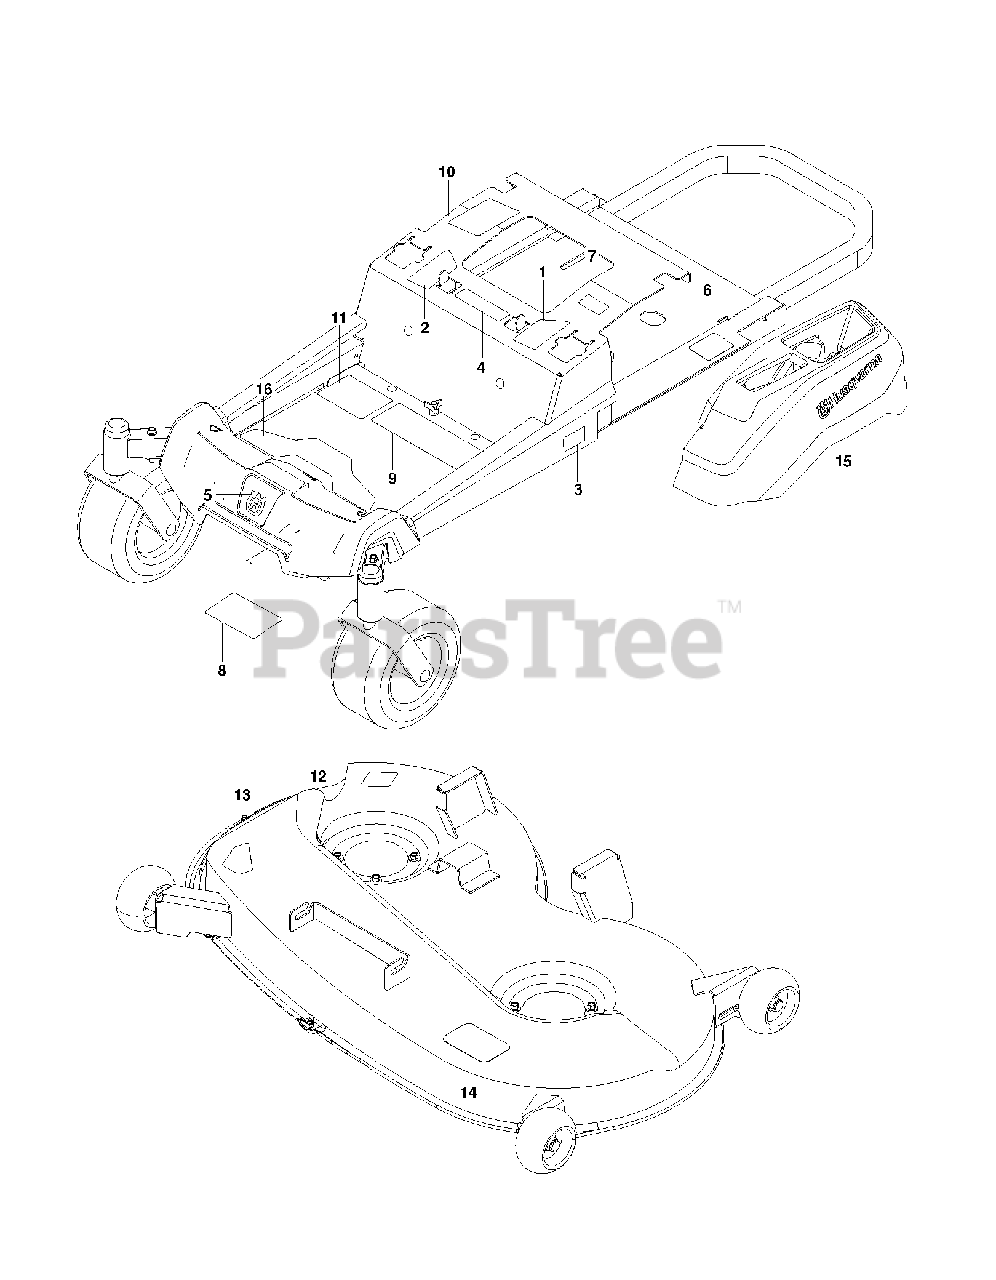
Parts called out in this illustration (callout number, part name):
1	DECAL.ZTR.RZ.THRTL/PRKBRK.V2.L
2	DECAL.ZTR.RZ.THRTL/PRKBRK.V2.R
3	DECAL.ZTR.SIDERAIL.Z246I.HU
4	EURO DECAL-BATTERY WARNIN6
5	DECAL.BADGE.55MM.CROWNH.HUSQ
6	DECAL, DO NOT TOW
7	DECAL, EXITING MOWER
8	DECAL, SERVICE
9	DECAL, SAFETY WARNING
10	DECAL.WARNING.CUST.RESP.E85.
11	DECAL.ZTR.STRTINSTR.SMARTSWITC
12	DECAL.DECK.6MIL./DEF.SHLD.WARN
13	DECAL, DECK DEFLECTOR, WARNING
14	DECAL, BELT ROUTING
15	DECAL.HUSQVARNA.210MM
16	PAD.RZ.FOOTREST.PLATE
